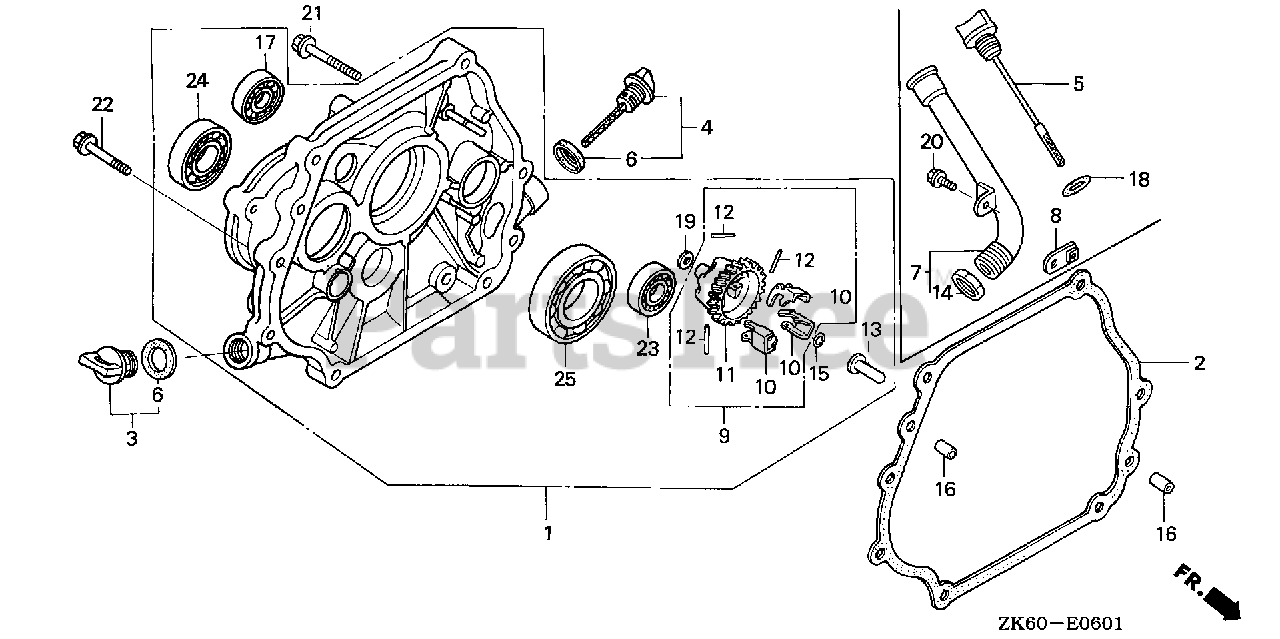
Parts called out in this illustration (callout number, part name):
1	COVER ASSY., CRANKCASE
2	GASKET, CASE COVER
3	CAP ASSY., OIL FILLER
4	CAP ASSY., OIL FILLER
6	GASKET, OIL FILLER CAP
9	GOVERNOR ASSY.
10	WEIGHT, GOVERNOR
11	HOLDER, GOVERNOR WEIGHT
12	PIN, GOVERNOR WEIGHT
13	SLIDER, GOVERNOR
15	CLIP, GOVERNOR HOLDER
16	PIN, DOWEL (8X12)
17	BEARING, RADIAL BALL (6202) (NTN)
19	WASHER, PLAIN (6MM)
22	BOLT, FLANGE (8X40)
23	BEARING, RADIAL BALL (6202)
24	BEARING, RADIAL BALL (6204) (TOYO)
25	BEARING, RADIAL BALL (6207)
